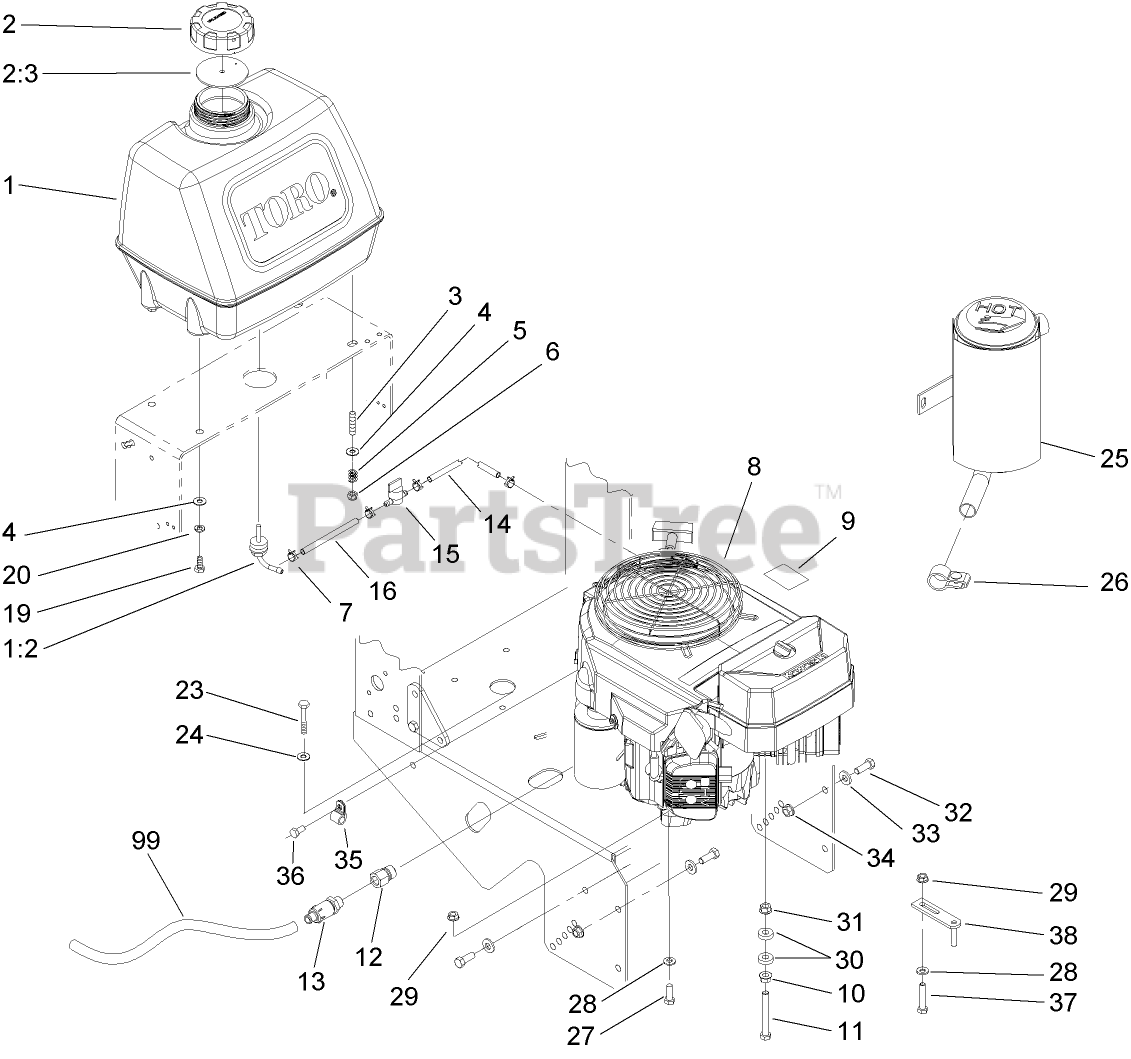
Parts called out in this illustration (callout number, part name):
1	FUEL TANK ASM
1:2	FITTING-FUEL, BULKHEAD
2	GAS CAP ASM
2:3	GASKET-CAP, GAS
4	WASHER-PLAIN
5	SPRING-TANK, FUEL
6	NUT-LOCK, NI
9	DECAL-WARNING
10	NUT-HF
11	SCREW-HH
12	Adapter
13	VALVE-DRAIN, OIL
14	HOSE-FUEL
15	VALVE-FUEL
16	HOSE-FUEL
19	SCREW-HH
20	WASHER-LOCK
23	SCREW-HH
24	WASHER-LOCK
25	MUFFLER
26	CLAMP-MUFFLER
27	SCREW-HH
28	WASHER-SPRING
29	NUT-HF
30	SPACER
31	NUT-LOCK, NI
32	SCREW-HH
33	WASHER-BELLEVILLE
34	NUT-HHF, WHIZ
35	Clip-Loom
36	SCREW-HH
37	SCREW-HH
38	GUIDE-BELT
99	HOSE-DRAIN, OIL
